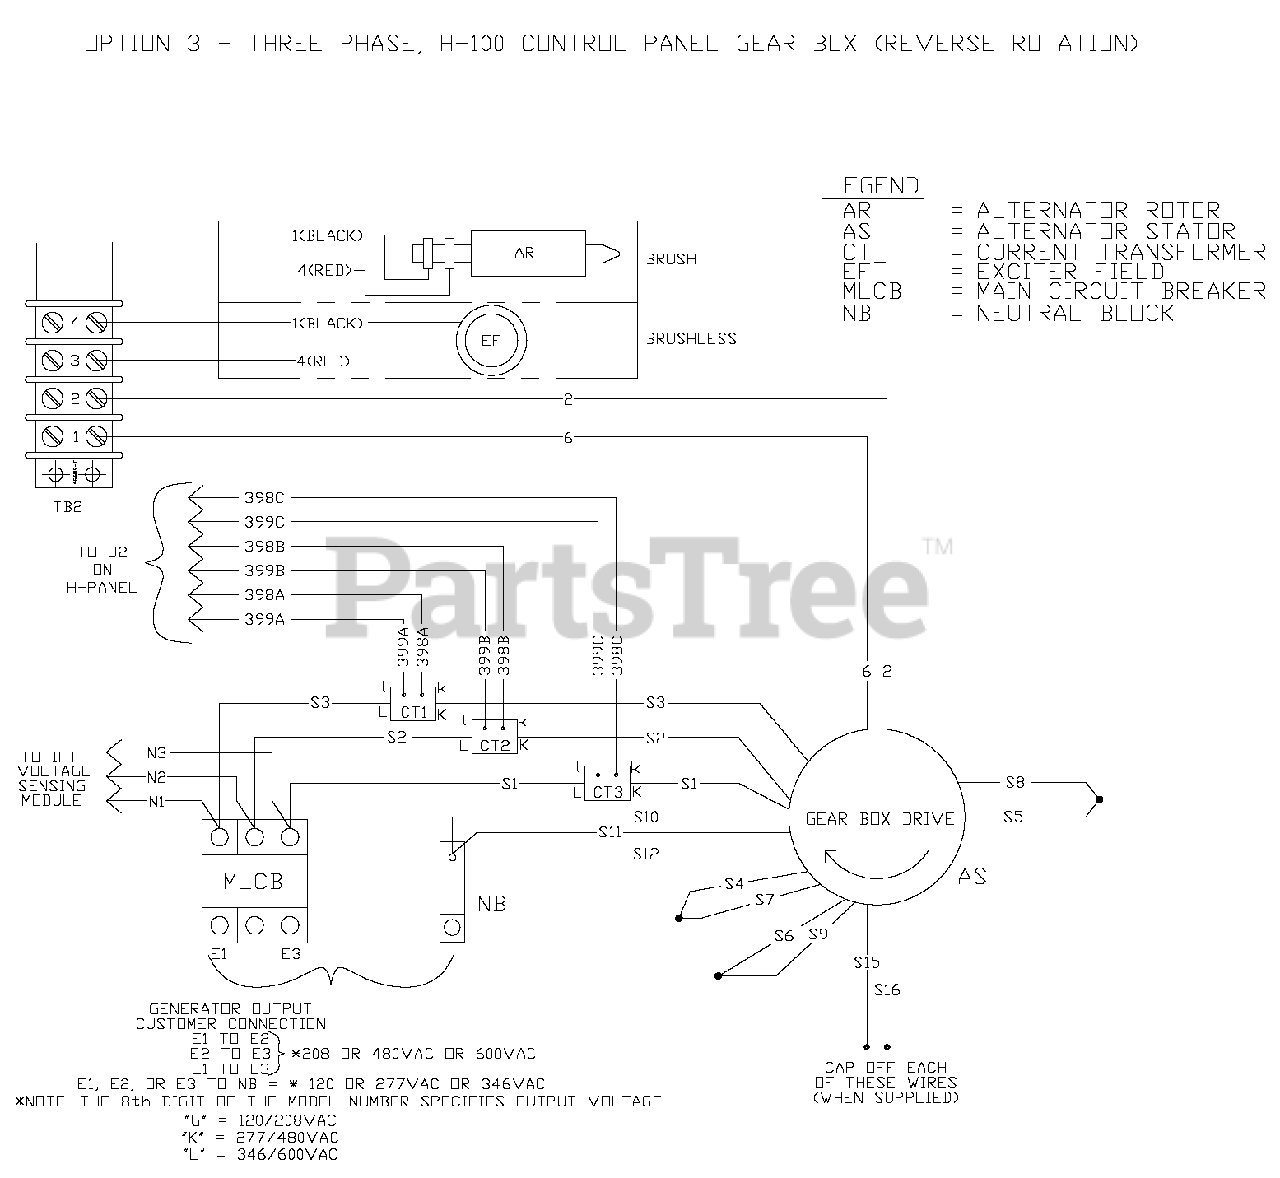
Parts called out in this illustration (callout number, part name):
1	ASSY ROTOR 2390 80KB3 CPL
2	ASSY STATOR 80KW 1PH 2P BRSHLS
3	EXITER FIELD 2" LG SPD CONN
4	ASSY EXCITER 2.0" STACK 2P
5	KEY SQ 3/8 X 3-1/4 STEEL
7	ASSY FLYWHEEL CPL
8	RING PRESSURE 390 STATOR CAN
9	KEY WOODRUFF #E
10	SCREW HHC M10-1.5 X 25 C10.9
11	WASHER LOCK M10
12	SCREW HHC M16-2.0 X 45 G8.8
13	SPACER .69 X 2.75 X .37 ST/ZNC
14	WASHER FLAT 1/4-M6 ZINC
15	WASHER LOCK M6-1/4
16	SCREW THF M6-1 X 16 N WA Z/JS
17	COLLAR SLIP FIT 390 MM
18	STUD M14-2.0 X 760 G5 ZINC
19	WASHER FLAT M14
20	WASHER LOCK M14
21	NUT HEX M14-2.0 G8 YEL CHR
22	PIN DOWEL 1/2 X 1-1/4
23	WASHER FLAT M12
24	WASHER LOCK M12
25	SCREW HHC M12-1.75 X 80 G10.9
26	SHIELD ALT EXCITER 390
27	COVER EXCITER SHIELD
28	CONDUIT FLEX 1.25" ID
29	CLAMP VINYL .312 X .203 Z
30	WASHER SHAKEPROOF INT #8
31	SCREW HHM #8-32 X 3/8
32	SCREW HHM #8-32 X 7/8
33	LUG RT-ANG #10/10-12
34	BRIDGE SUPPORT DIODE 15"
35	CAP END ROTOR 390MM
36	ASSY BRIDGE RECTIFIER
37	SLEEVING UL #0 .330 ID (3" LG)
38	TIE WRAP UL 3.9" X .10" BLK
39	TIE WRAP UL 17.7 X .35 BLK HT
40	REAR BEARING CARRIER CPL
41	SCREW HHC M12-1.75 X 60 G10.9
42	SCREW 1/4-20 X 5/8" TAPTITE SS
43	BUSHING SNAP SB-2.5-31
44	MOUNT CT'S 5.4L 100KW
45	TRANSFORMER
46	SCREW PHTT #6-32 X 1/2 ZYC
47	WASHER LOCK #6
48	SCREW HHC M6-1.0 X 20 G8.8
49	NUT HEX M6 X 1.0 G8 YEL CHR
50	BEARING BALL 6212 SEALED
51	SHROUD UPPER ALTERNATOR EXCITR
52	SHROUD CENTER ALTERNATR EXCITR
53	SHROUD LOWER ALTERNATOR EXCITR
60	ASSY SCROLL 390 X 60MM CPL
61	SHROUD ALT SHEET METAL CPL 2P
62	SCREEN, 390 SAE ALT 60MM WIDE
63	BRACKET SAE SCROLL TENSIONER
64	VINYL TRIM 1/8" GAP
65	WASHER, SPLIT 1/4"-M6
66	WASHER FLAT 1/4 ZINC
67	SCREW HHC M6-1.0 x 25 LONG
68	SCREW HHC M6-1.0 X 16 G8.8
69	SCREW SWAGE 1/4-20 X 1/2 Z/YC
